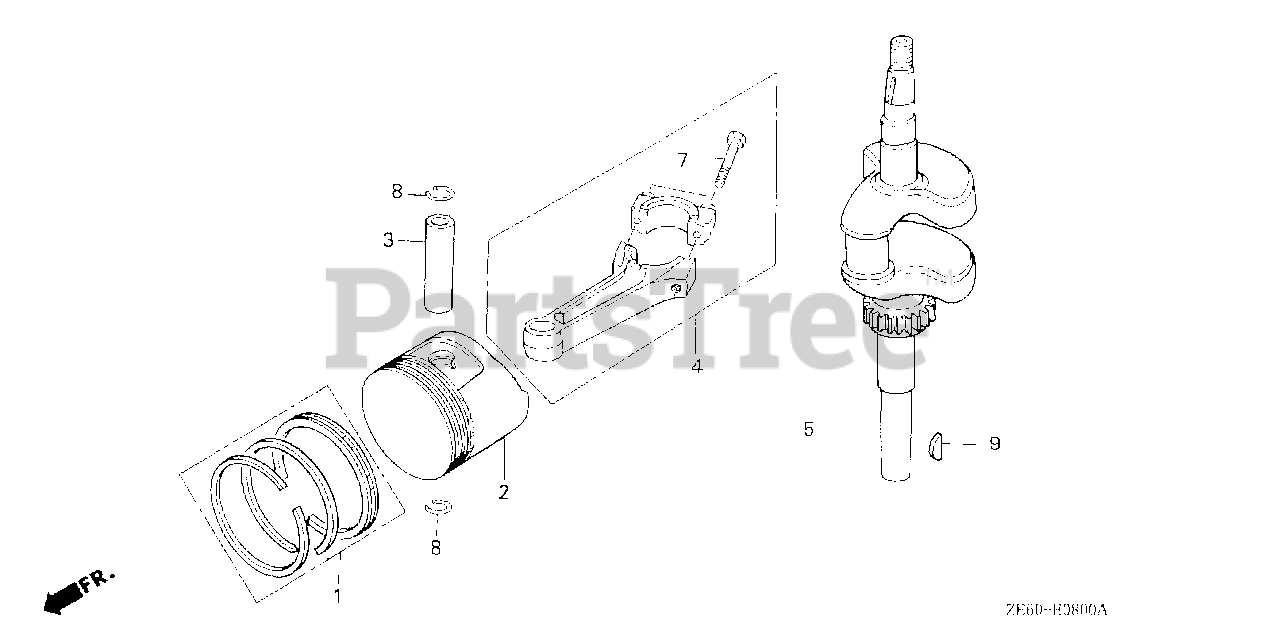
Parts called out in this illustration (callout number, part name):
1	RING SET, PISTON (STD) (NIPPON)
1	RING SET, PISTON (0.25) (NIPPON)
1	RING SET, PISTON (0.50) (NIPPON)
1	RING SET, PISTON (0.75) (NIPPON)
2	PISTON (STD)
2	PISTON (0.25)
2	PISTON (0.50)
2	PISTON (0.75)
3	PIN, PISTON
4	ROD ASSY., CONNECTING
4	ROD ASSY., CONNECTING (0.25 LOWER SIZE)
5	CRANKSHAFT
7	BOLT, CONNECTING ROD
8	CLIP, PISTON PIN (13MM)
